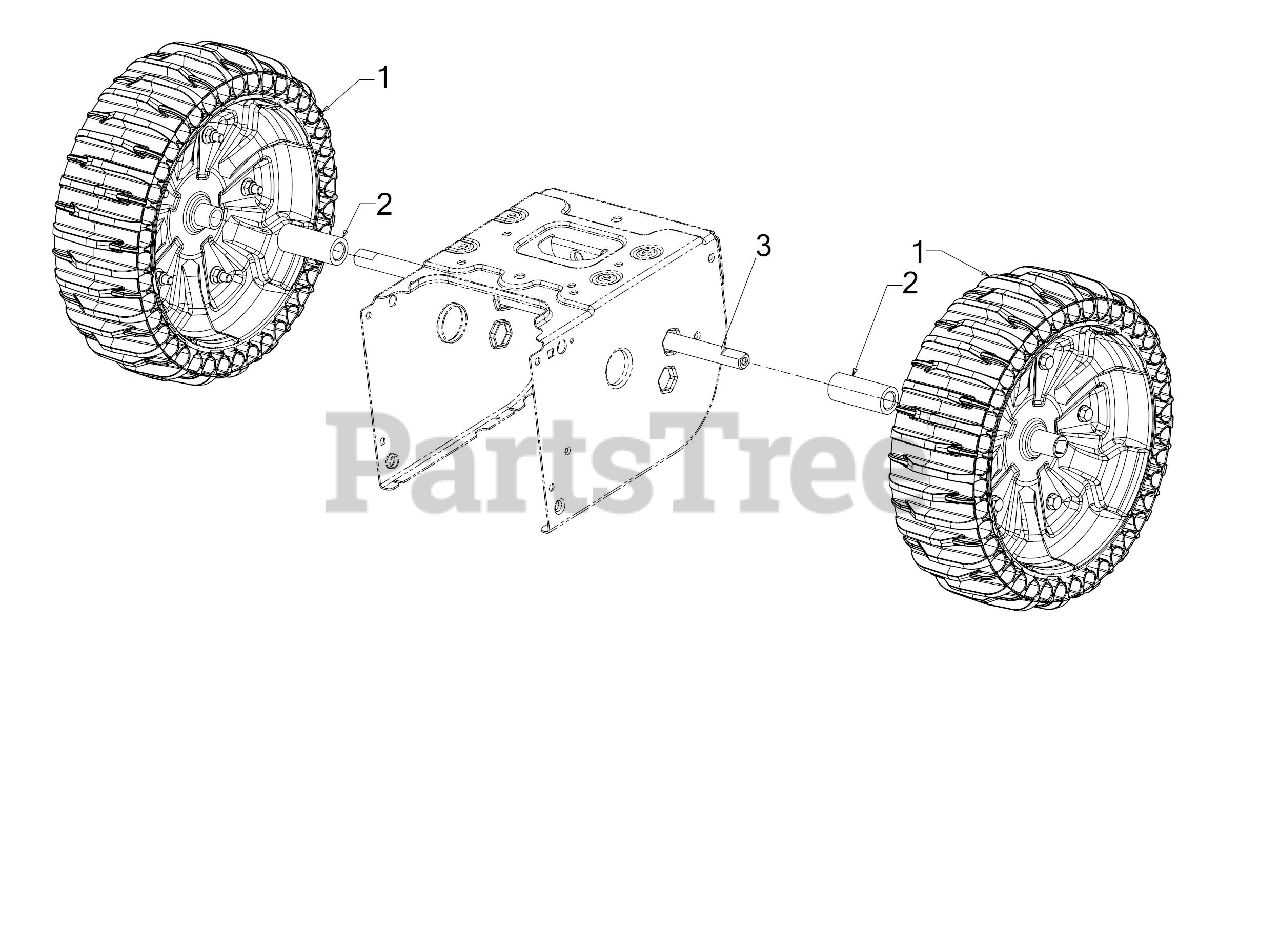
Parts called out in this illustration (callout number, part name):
1	SCREW 3/8-16 x .875 GR5
2	WHEEL SPACER 1.25ODX.75X3.00
3	WHEEL AXLE SHAFT .75 x 22"
